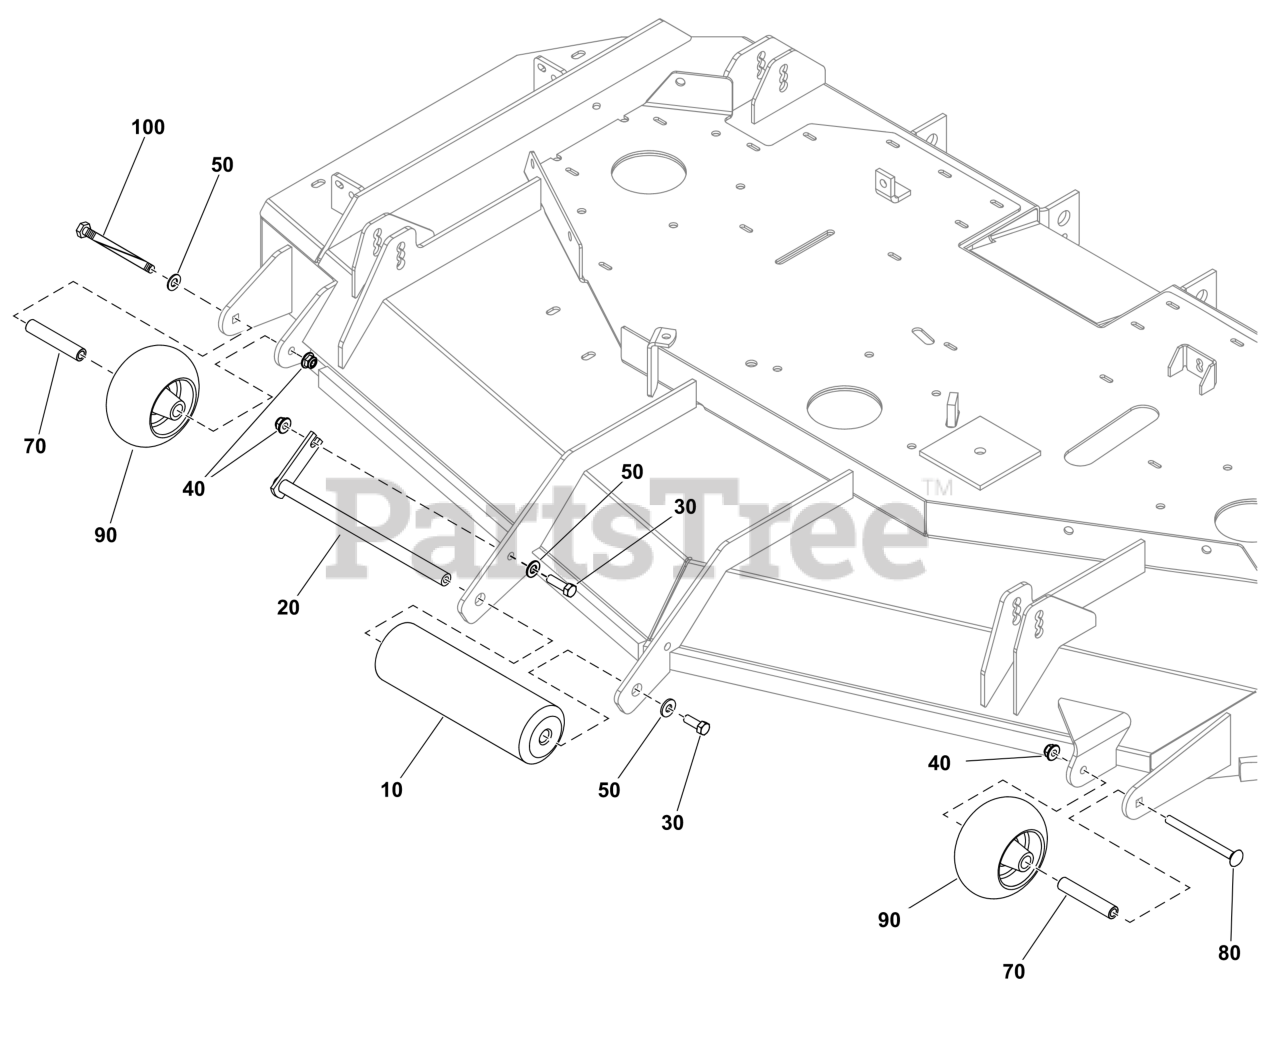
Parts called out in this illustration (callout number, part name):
10	ROLLER, DECK
20	WELD, BRACKET, ROLLER
30	BOLT, 3/8-16 X 1" GD5
40	NUT, 3/8-16 HEX NYLOCK
100	BOLT, 3/8-16 X 4-1/2
